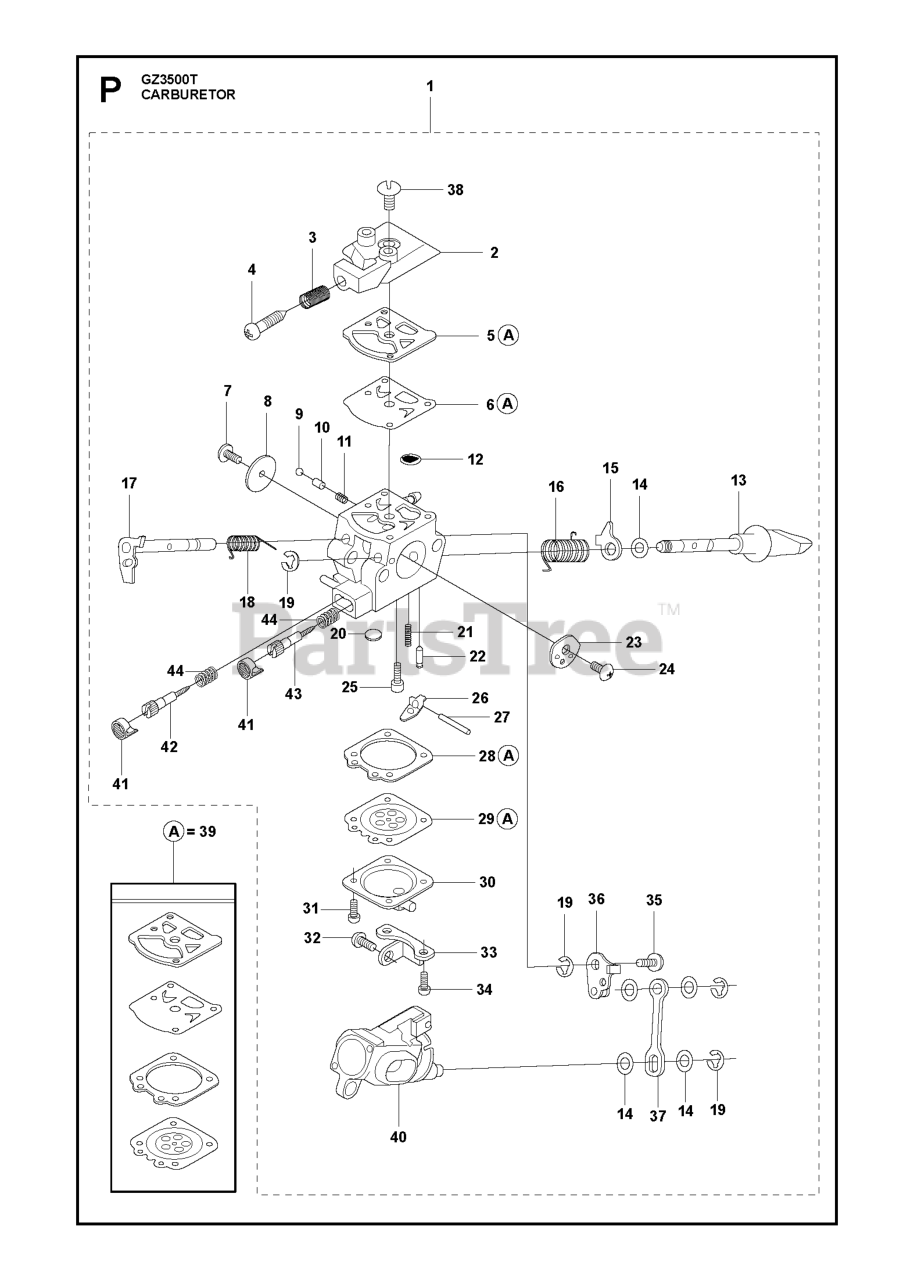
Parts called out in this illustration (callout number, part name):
1	CARB ASSY
2	COVER PUMP
5	GASKET
6	DIAPHRAGM
7	SCREW
9	BALL
10	PISTON
11	SPRING
12	SCREEN
17	SHAFT ASST THRO
18	SPRING RETURN
21	SPRING
22	VALVE INLET
23	CHOKE VALVE
24	SCREW
28	GASKET
29	DIAPHRAGM
31	SCREW ASSY
34	SCREW ASSY
35	SCREW
36	LINK ASSY THROT
37	ROD, LINK
39	GASKET, KIT
40	BODY ASSY AIR V
41	CAP LIMITER
43	NEEDLE H
